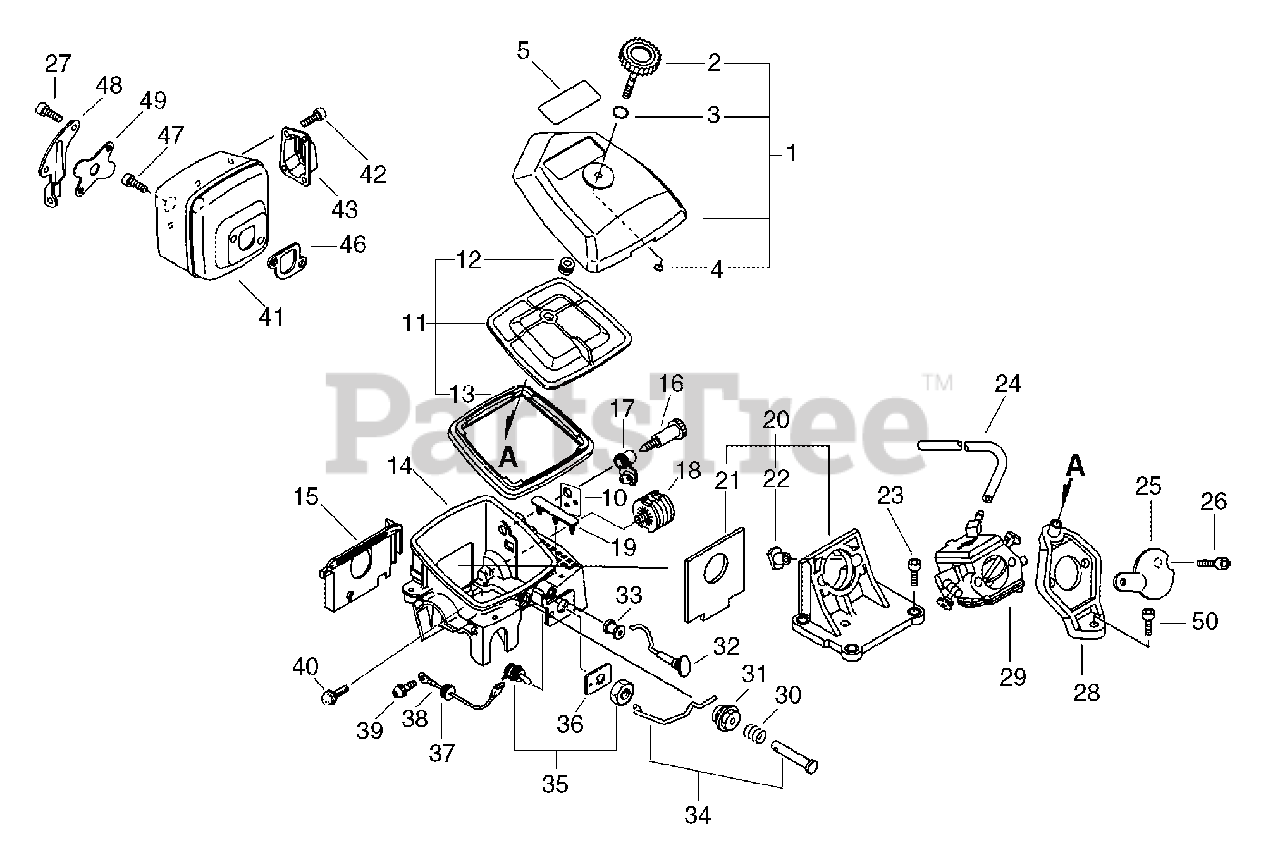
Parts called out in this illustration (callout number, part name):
1	AIR FILTER COVER ASSY
2	THUMBSCREW
3	O-RING - 10
4	O-RING - 3
5	LABEL - MODEL
10	LABEL - ADJUSTING
11	FILTER, AIR
14	CASE, CARBURETOR
15	PLATE, GUIDE
16	SCREW, IDLE ADJUST
19	PLUG
20	INSULATOR, INTAKE
21	SEAL, DUST
22	NUT
23	SCREW - 5X25
24	PIPE - IMPULSE
25	PLATE, PREVENT
26	SCREW - 5X55
27	SCREW - 5X14
28	BRACKET, AIR CLEANER
29	CARBURETOR HDA-153B
31	GUIDE, THROTTLE ROD
32	ROD, CHOKE
34	ROD, THROTTLE
35	IGNITION SWITCH ASSY
36	LABEL - STOP
38	LEAD - GROUND
39	SCREW - 4X8
40	SCREW - 4X8
42	SCREW - 4X10
43	LID, MUFFLER
46	GASKET, EXHAUST
47	SCREW - 6X20
48	BRACKET, MUFFLER
49	COVER, MUFFLER
50	SCREW - 5X20
